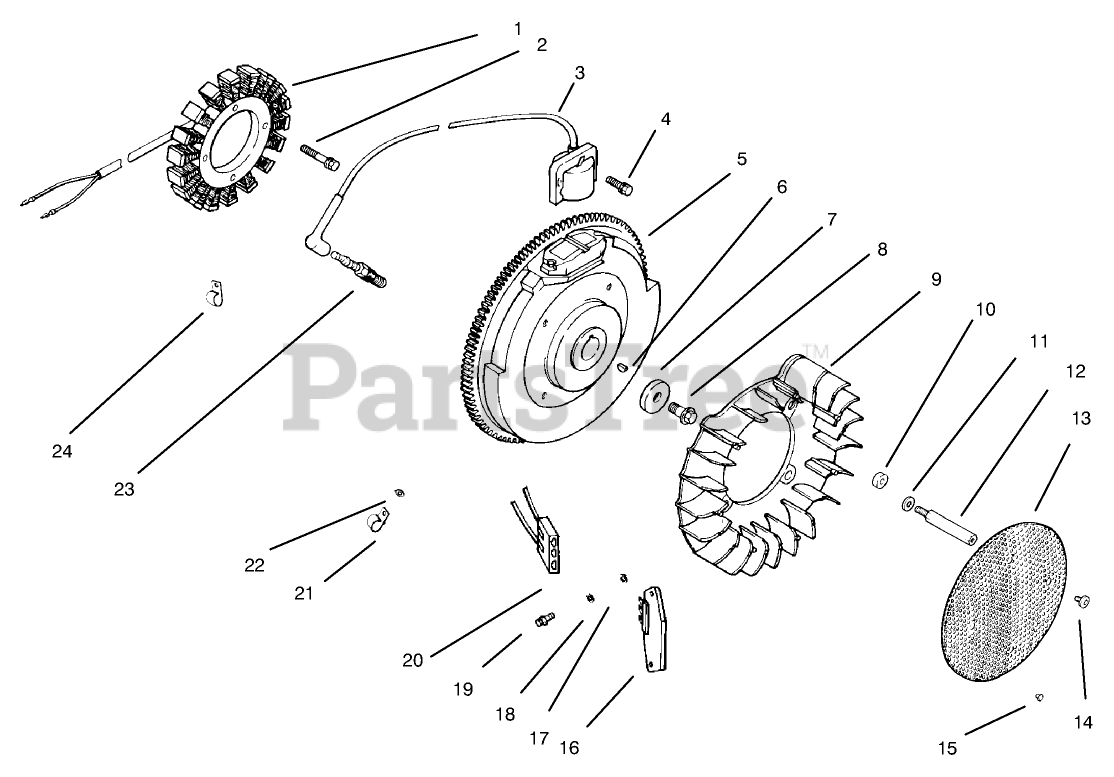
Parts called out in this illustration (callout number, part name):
1	Stator-15 Amp
2	Screw
3	Module-Ignition
4	Screw
5	Flywheel
6	Key
7	Washer
8	Screw
9	Fan
10	Spacer-Fan
11	Washer
12	Stud
13	Screen-Grass
14	Screw
15	Screw-Set
16	Rectifier-Regulator
17	Washer
18	Washer
19	Screw
20	Connector
21	Clip
22	Washer
23	Plug-Spark
24	Clip
